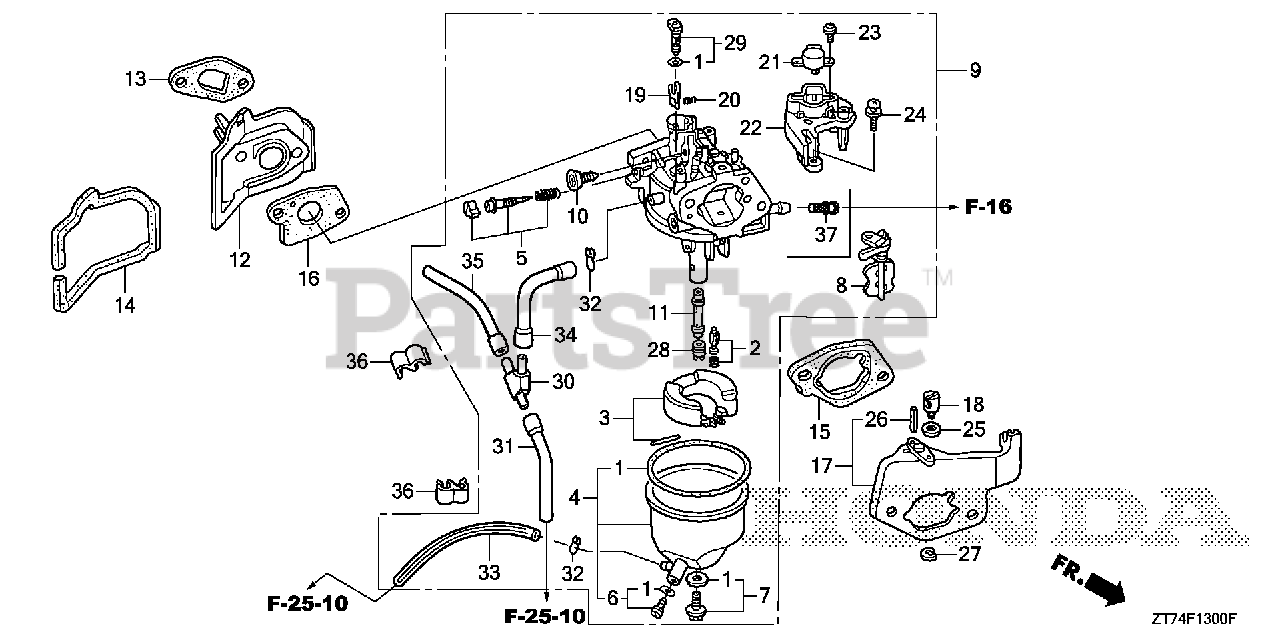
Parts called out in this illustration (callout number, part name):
1	GASKET SET
2	VALVE SET, FLOAT (SEAT NOT INCLUDED)
4	CHAMBER SET, FLOAT
5	SCREW SET, PILOT
6	SCREW SET, DRAIN
9	CARBURETOR ASSY. (BEA0D A)
10	SCREW, THROTTLE STOP
11	NOZZLE, MAIN (CARBURETOR NO.)
12	INSULATOR, CARBURETOR
13	GASKET, INSULATOR
14	SEAL, CARBURETOR INSULATOR
15	GASKET, AIR CLEANER
16	GASKET, CARBURETOR
17	STAY, CHOKE
18	HOLDER, CABLE
19	LEVER, LINK
20	SPRING, COMPRESSION COIL
21	MOTOR, THROTTLE CONTROL (CARBURETOR NO.)
22	BRACKET, THROTTLE MOTOR
23	SCREW-WASHER (3X8)
24	SCREW-WASHER (4X10)
25	WASHER, PLAIN (6MM)
26	PIN, SPRING (2X18)
27	E-RING (5MM)
28	JET, MAIN (#72)
28	JET, MAIN (#75)
28	JET, MAIN (#70)
29	JET SET, PILOT (#45)
30	JOINT, AIR VENT TUBE (CARBURETOR NO.)
31	TUBE, AIR VENT (CARBURETOR NO.)
32	CLIP, TUBE (C6.5) (CARBURETOR NO.)
33	BULK HOSE, VINYL (3.5X6.5X8000) (3.5X6.5X200) (CARBURETOR NO.)
34	BULK HOSE, VINYL (4X7X8000) (95003-07(95003-07001-60M) (CARBURETOR NO.)
35	BULK HOSE, VINYL (4X7X8000) (95003-07(95003-07001-60M) (CARBURETOR NO.)
36	CLAMP, TUBE (7.5X2)
37	SCREEN, FUEL STRAINER
